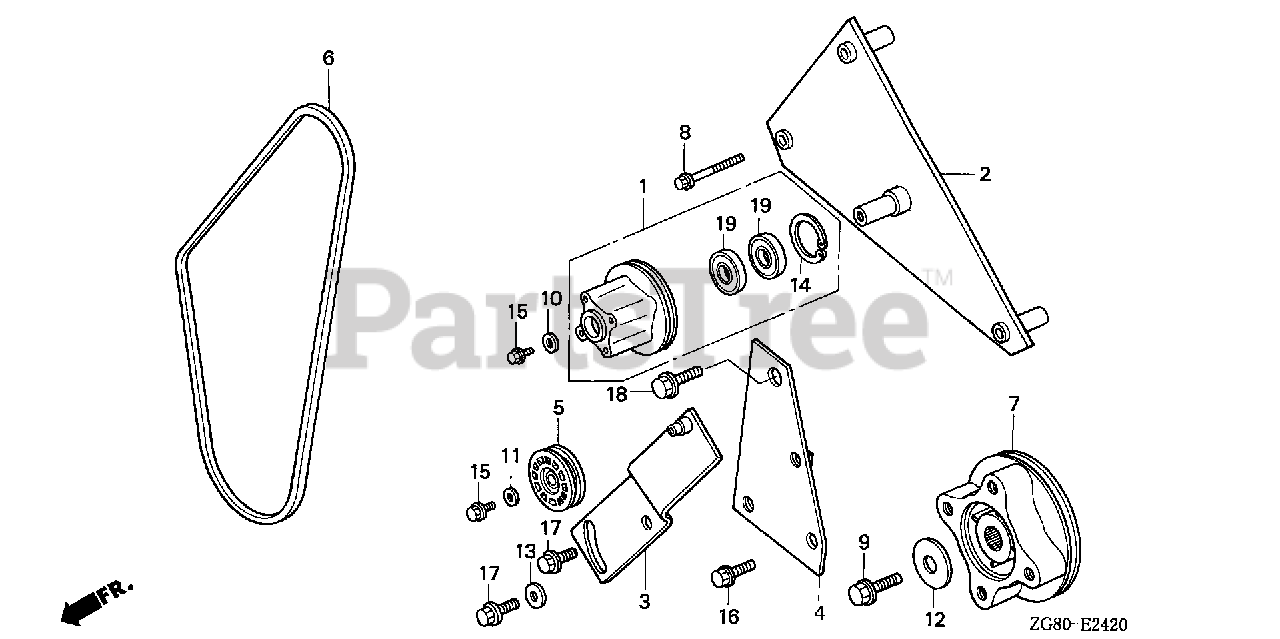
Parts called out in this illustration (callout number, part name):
1	PULLEY ASSY., COOLING FAN
2	BRACKET, COOLING FAN
3	ARM, TENSION
4	PLATE, TENSIONER ARM
5	PULLEY, TENSIONER (65MM)
6	BELT, ALTERNATOR (BANDO)
7	JOINT, PROPELLER SHAFT
8	BOLT, FLANGE (6X50)
9	BOLT, SPECIAL (10MM)
10	WASHER, GEARSHIFT DRUM SIDE
11	WASHER (6MM)
12	WASHER (10.5X40X4)
13	WASHER, PLAIN (10MM)
14	CIRCLIP (INNER) (32MM) (NOT AVAILABLE)
15	BOLT, FLANGE (6X12)
16	BOLT, FLANGE (8X20)
17	BOLT, FLANGE (10X20)
18	BOLT, FLANGE (10X20)
18	BOLT, FLANGE (10X25)
19	BEARING, RADIAL BALL (6201UU)
